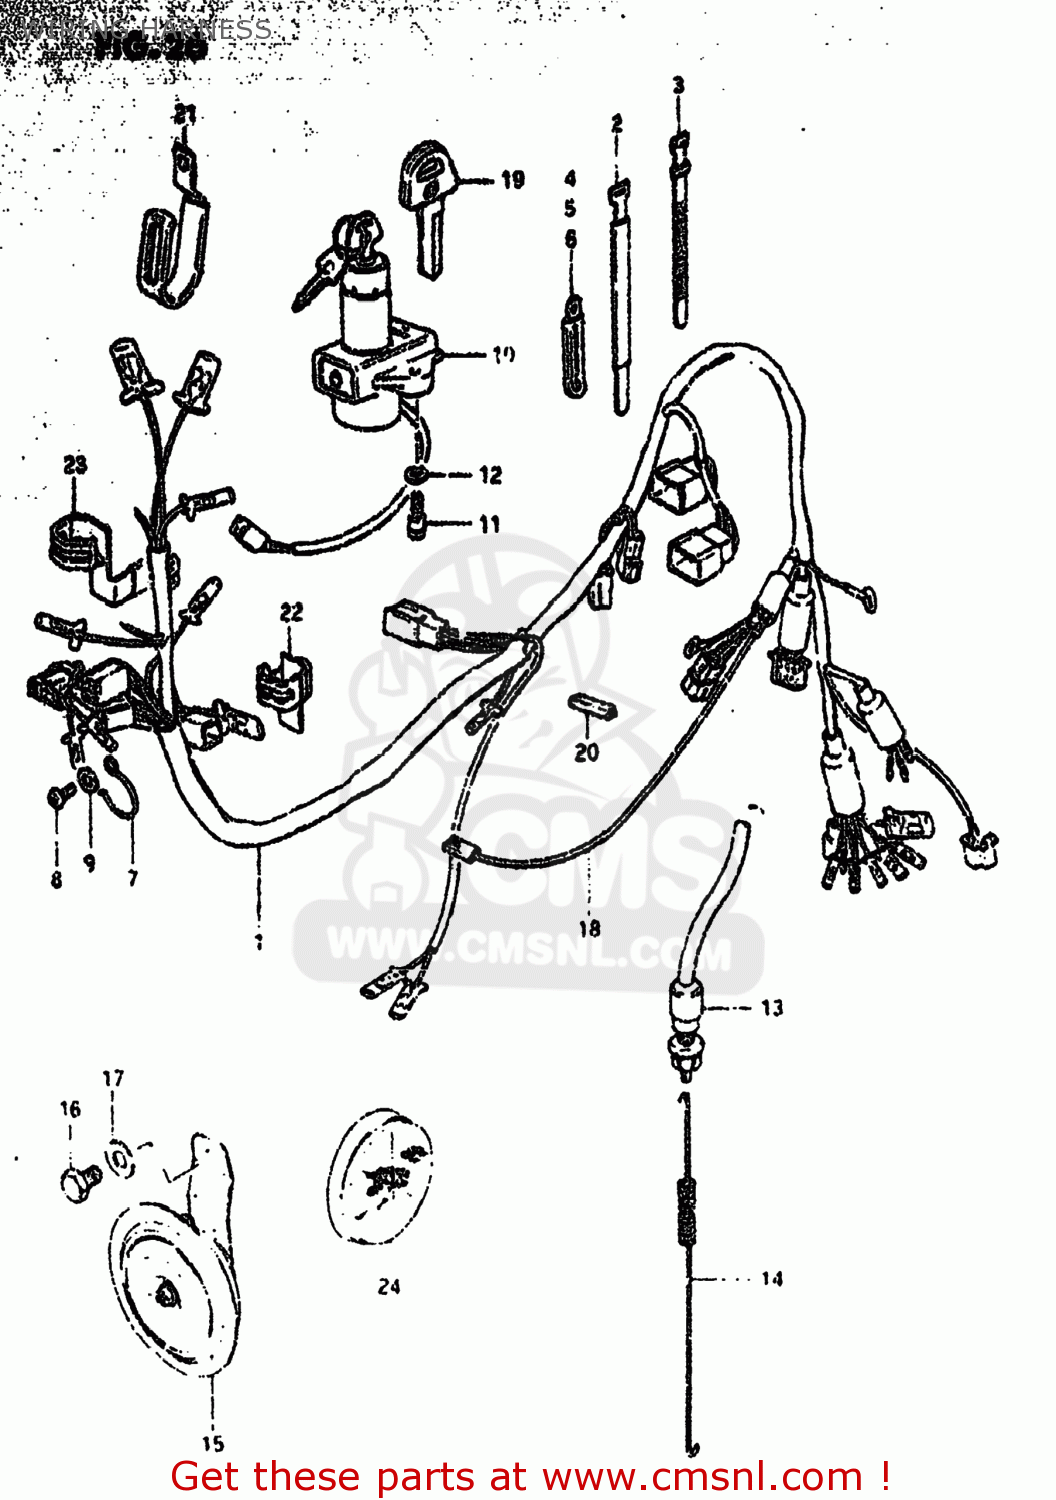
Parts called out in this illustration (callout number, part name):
1	HARNESS,WIRING
2	CLAMP
3	CLAMP(L:120)
4	CLAMP
5	CLAMP
6	CLAMP
7	GUIDE,WIRING HARNESS
8	SCREW 6X12
9	WASHER
10	LOCK ASSEMBLY,STEERING
11	BOLT
12	LOCK WASHER
13	SWITCH ASSEMBLY,STOP LAMP
14	SPRING
15	HORN ASSEMBLY
16	BOLT 8X12
17	WASHER
18	WIRE
19	KEY,BLANK
20	PROTECTOR,WIRING HARNESS
21	CLAMP,WIRING HARNESS
22	CLAMP,WIRING HARNESS
23	CLAMP,WIRING HARNESS
24	REFLEX REFLECTOR,RR
